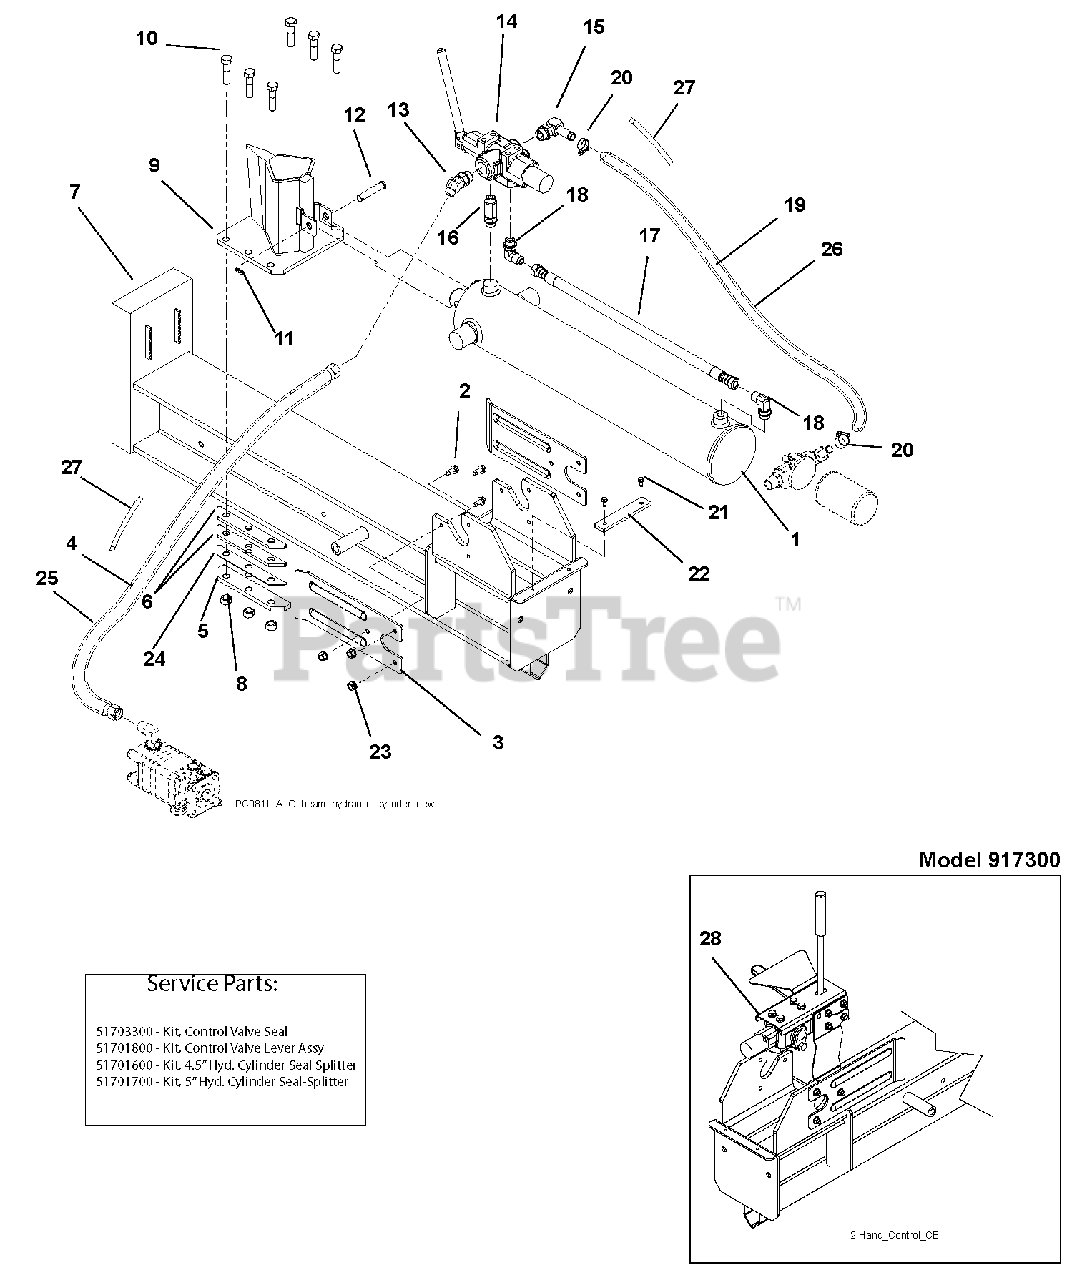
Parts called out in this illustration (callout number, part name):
1	CYLINDER,4.5 W/DECALS
1	KIT,4.5" HYD CYL SEAL-SPLITTER
1	CYLINDER, 5' W/DECALS
1	KIT, 5" HYD CYL SEAL-SPLITTER
2	@BLT-HEX .31-18X1.00 GR5 YWZC
3	PLATE,STRIPPER
4	HOSE, ASM - 46"
5	RETAINER,WEDGE
6	SPACER, WEDGE
7	WLDMT, SPLITTER BEAM
7	WLDMT, CE SPLITTER BEAM
8	@NUT-LK-CTR .50-13 YWZC
9	WLDMT, SPLITTER WEDGE
10	BLT-RDHDSQNKFTH.50-13X2 G8YWZC
11	CLIP, SPRING
12	PIN-CLEV .494X2.50 BRIGHT ZINC
13	FTG,HYD 6802-8-10
14	VALVE CONTROL-SPLITTER
14	KIT,CONTROL VALVE SEAL
14	KIT,CONTROL VALVE LEVER ASSY
15	FTG,HYD 4601-10-10
16	FTG,HYD 6403-NWO-8-8-L
17	HOSE, HYD - 22"
18	FTG,HYD 6801-8-8
19	HOSE,HYD RETURN 10LOLA X 53"
20	CLAMP,.88 DIA. HOSE
21	SCR-TAP .25-20X.50 HWH TR YWZ
22	SPACER, CYLINDER
23	@NUT-LK-TOP-FLG .31-18 YWZC
24	SHIM,SPLITTER WEDGE
25	SLV, PROTECTIVE - 50"
26	SLV, PROTECTIVE - 24"
27	CABLE TIE LG 5-1/2
28	VALVE, CONTROL - CE SPLITTER
